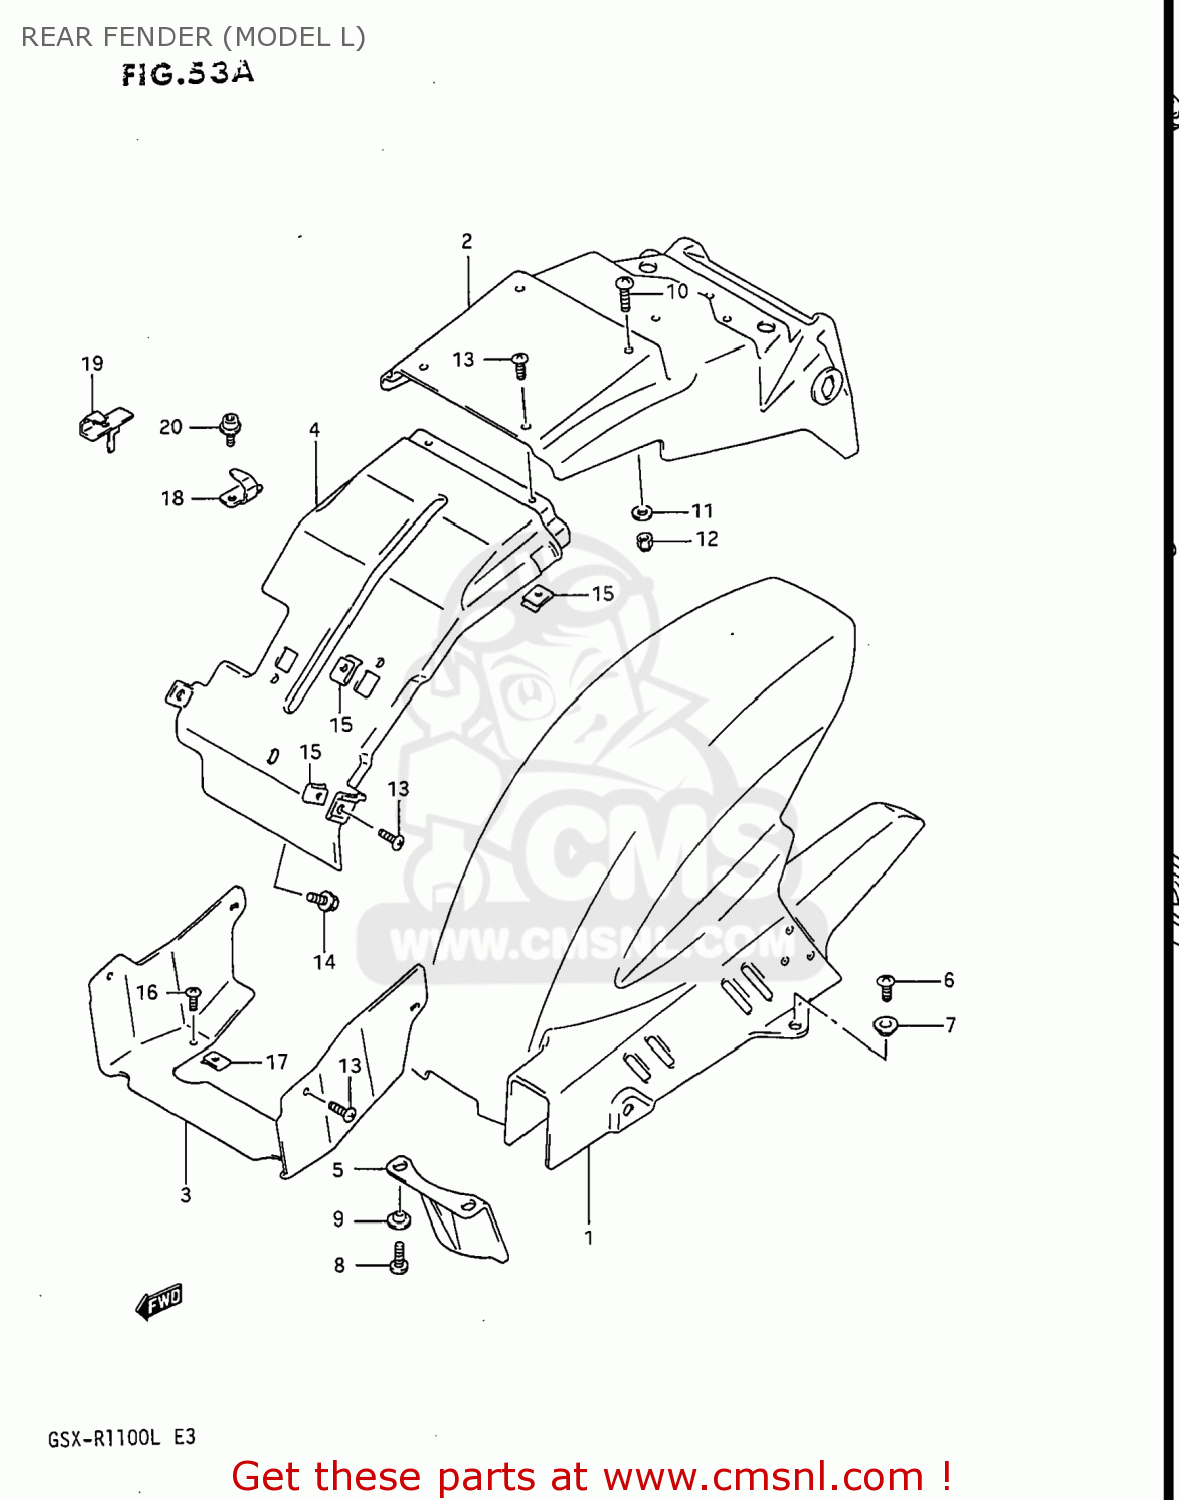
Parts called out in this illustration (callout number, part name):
1	FENDER,RR LWR
2	FENDER,RR UPR
3	FENDER,REAR
4	FENDER,RR UPR FR NO.2
5	GUARD,RR UNIT MUD
6	SCREW
7	WASHER
8	SCREW
9	WASHER,LOCK
10	SCREW
11	WASHER
12	NUT 6MM
13	SCREW, FRONT & REAR
14	BOLT
15	NUT,HEADLAMP HOUSING,UPPER
16	SCREW, FRONT & REAR
17	NUT,HEADLAMP HOUSING,UPPER
18	HOLDER,HELMET
19	HOLDER,HELMET,RIGHT
20	BOLT
